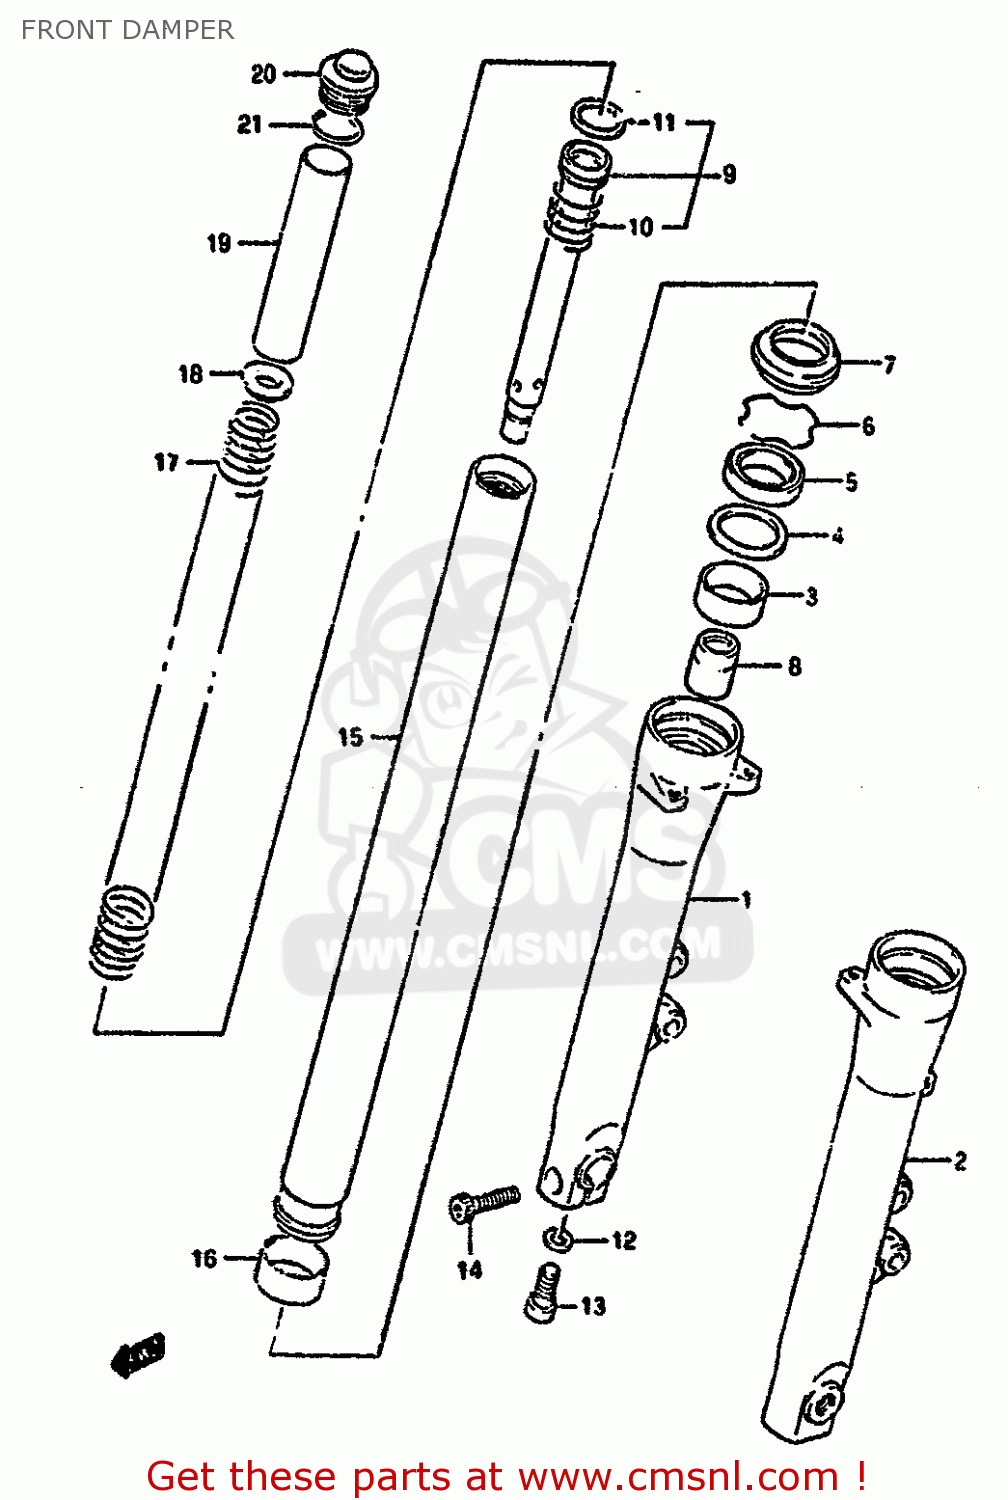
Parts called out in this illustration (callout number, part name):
1	TUBE,OUTER,RIGHT
2	TUBE,OUTER,L
3	METAL,SLIDE
4	WASHER
5	OIL SEAL,FRONT FORK
6	RING,STOPPER
7	SEAL,DUST
8	PIECE,OIL LOCK
9	CYLINDER
10	SPRING,REBOUND
11	RING,PISTON
12	GASKET (NAS)
13	BOLT(14X25)
14	BOLT
15	TUBE,INNER
16	PISTON
17	SPRING,MAIN
18	GUIDE,SPRING
19	SPACER
20	CAP,FORK
21	O RING
